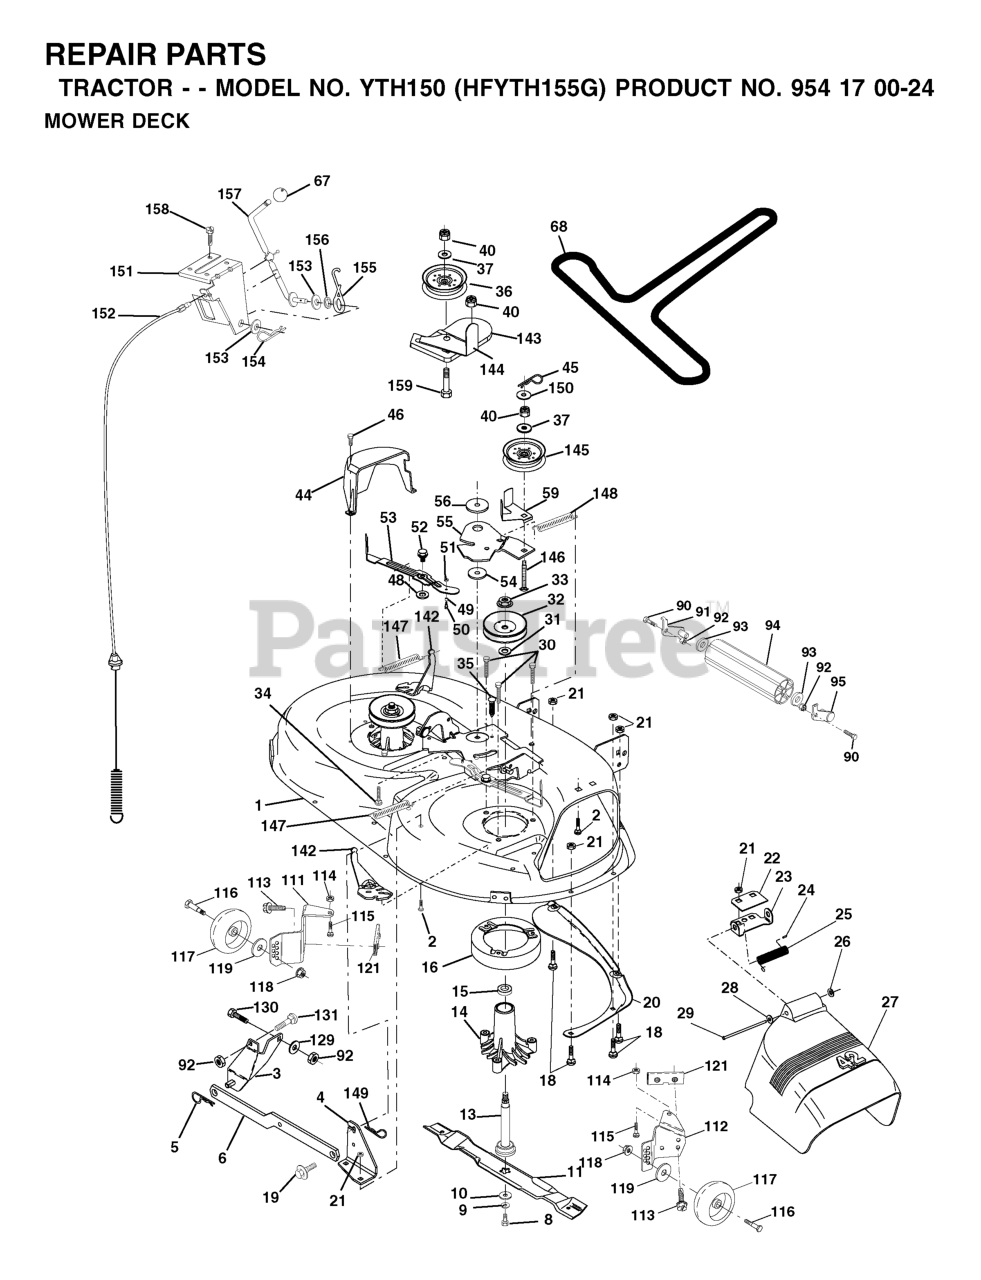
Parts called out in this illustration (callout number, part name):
1	42" DECK KIT
2	RP BOLT 5/16-18 X3/4 ZN/YEL GR
3	BRKT ASM SWAY BAR
4	BRACKET SWAY BAR 42" DECK
5	RETAINER-SPRNG RB
6	REAR SUSP ARM
8	BLADE BOLT
9	LOCKWASHER
10	WASHER.BLADE
11	Blade Mower 42" High Perf.
13	SHAFT ASM VENT
14	HOUSING.MANDREL.VENTED (MACHD)
16	STRIPPER
18	BOLT
19	BOLT SHD 5/16-18
20	BAFFLE.VORTEX
21	LOCKNUT
22	STIFFENER BRACKET
23	DEFLECTOR BRACKET
24	CAP-SLEEVE LT
25	SPRING TORSION
26	NUT PUSH M
27	SHIELD DEFLECTOR
28	Washer 11/32 x 5/8 x 16 Ga SD
29	ROD.HINGE
30	SCREW THDROL ROLLING WASHER HD
31	WASHER
32	PULLEY/MANDREL
33	NUT
35	FASTENER.XMAS.TREE
36	FLAT IDLER PULLEY
37	WASHER
44	GUARD MANDREL LH BLACK
45	RETAINER M
46	SCREW.1/4-20X5/8
49	ROLLER ASM CAM FOLLOWER
52	BOLT.SHOULDER.5/16-18
53	ARM
54	HARDENED WASHER
55	ARM IDLER 42" MOWER LT/YT
56	SPACER.RETAINER.MOWER
59	GUARD, BELT
67	KNOB T (3/8 HOLE)
68	BELT V SECONDARY
90	BOLT
91	BRACKET LH (A)
92	NUT
93	Washer 1 17/32 X 7/8 X 16 Ga
94	NOSE ROLLER
95	BRACKET RH (B)
111	BRACKET WHEEL GAUGE LH 42" DK
112	BRACKET WHEEL GAUGE RH 42" DK
113	Screw Tapping 5/16-18 Unc
114	NUT
115	BOLT.CARR.5/16-18X1/2
116	BOLT M
117	WHEEL.GAUGE.STANDARD
118	LOCKNUT
119	WASHER.5/16.FLAT.STE.STD.
121	BRACKET.EXTRUDED.GAGE.WHEEL
129	WASHER
131	BOLT D
142	ARM SPRING BRAKE MOWER
143	BRACKET, ARM IDLER
144	DNO KEEPER.BELT.42".CLUTCH.CBL
145	PULLEY
146	BOLT, CARRIAGE IDLER BLACK
147	SPRING EXTENSION
148	IDLER RETURN SPRING
149	SPRING.RETAINER.YELLOW.ZINC
151	BRACKET.CLUTCH.CABLE
152	CLUTCH CABLE 42"
153	WASHER FLAT 3/8"
154	SPRING RETAINER
155	SPRING RETENTION LEVER
156	SPACER.CLUTCH.CABLE
157	ROD CLUTCH CABLE 3/8"
158	SCREW LT
